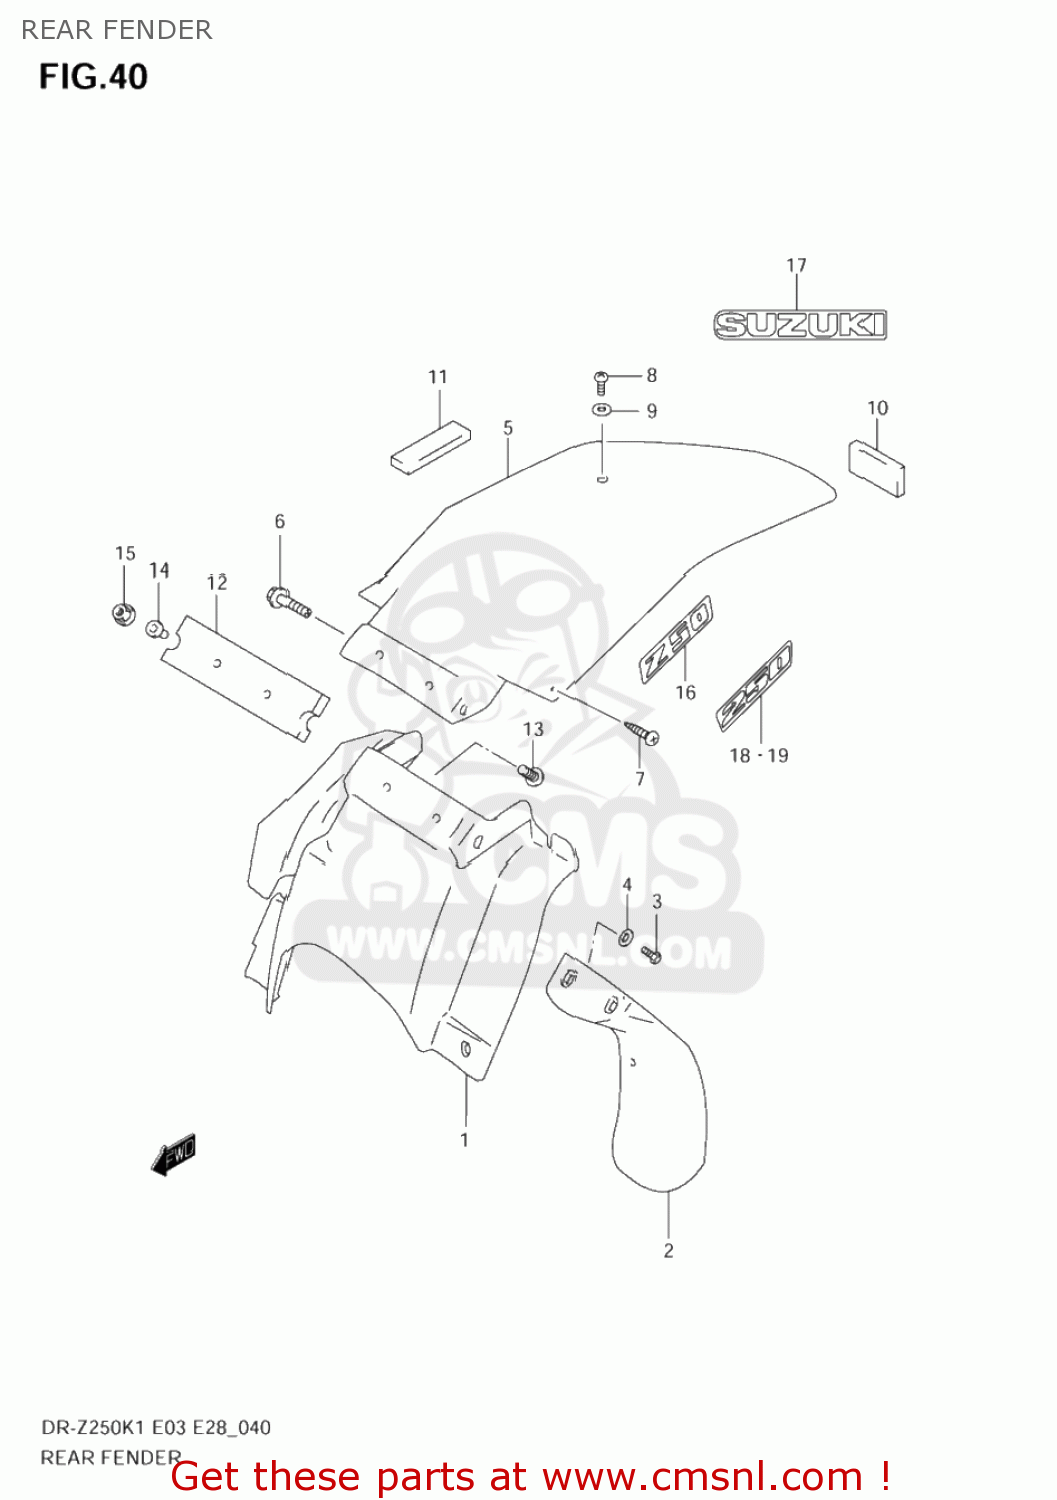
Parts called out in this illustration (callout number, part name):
1	BODY,RR FENDER FR
2	GUARD,RR FENDER MUD
3	SCREW 6X12
4	WASHER
5	BODY, RR FENDER RR (YELLOW)
6	BOLT 6X12
7	SCREW(6X16)
8	SCREW(6X20)
9	WASHER
10	CUSHION
11	PROTECTOR,RR FENDER
12	CUSHION,RR FENDER FR
13	SCREW 5X20
14	WASHER
15	NUT
16	EMBLEM
17	EMBLEM,RR
18	EMBLEM,R
19	EMBLEM,L
